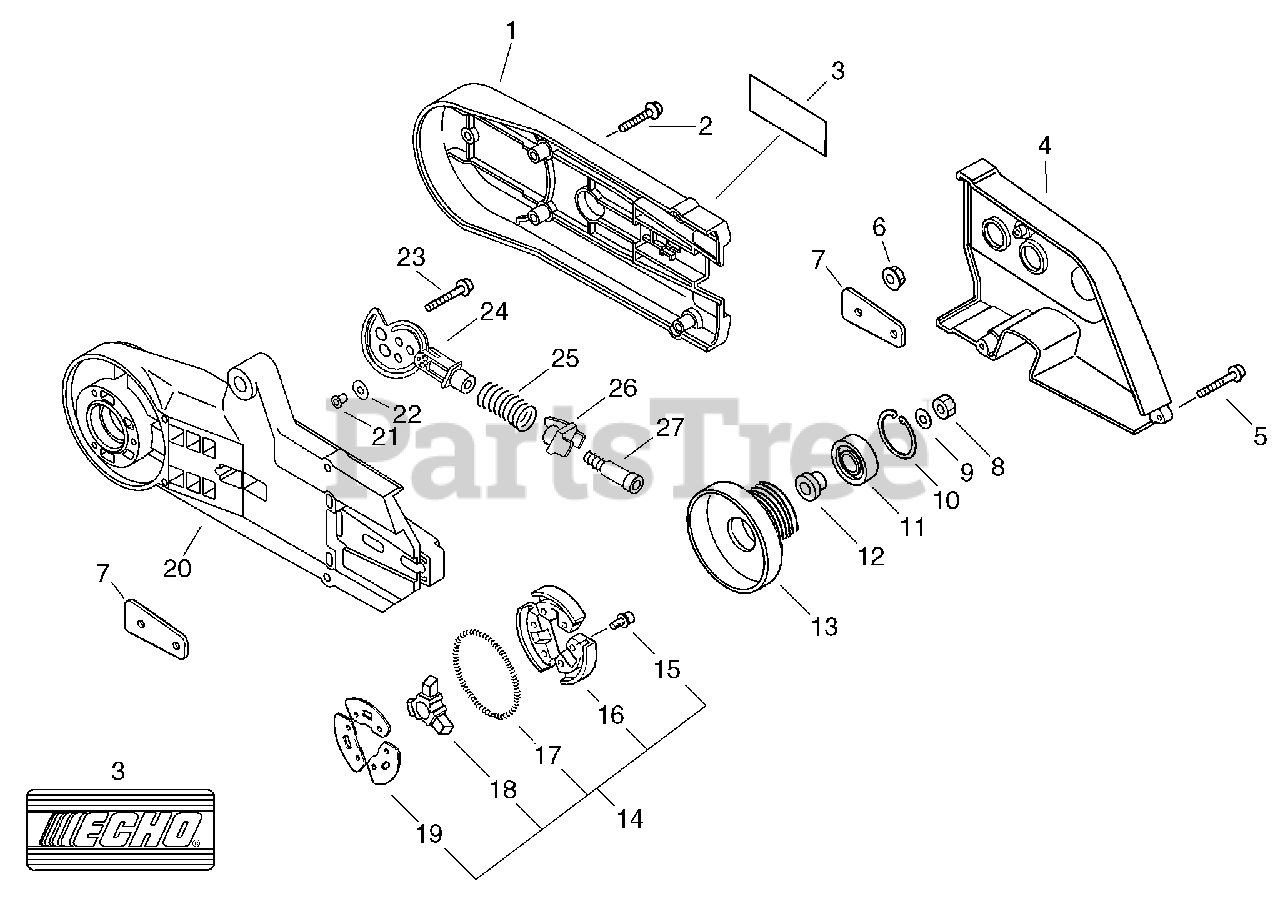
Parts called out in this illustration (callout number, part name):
1	COVER, GEAR
2	SCREW 5×25
3	LABEL - ECHO
4	COVER, V-BELT
5	SCREW 5×25
6	NUT, FLANGE M8×1.25
7	SPACER, ARM
8	NUT 8 LH
10	RING, SNAP 28
11	BEARING, BALL 6001 DDU
12	COLLAR - 10
13	DRUM, CLUTCH
14	CLUTCH ASSY
15	BOLT 4×6
16	SHOE SET, CLUTCH (3PCS)
17	SPRING, CLUTCH
18	BOSS, CLUTCH
19	PLATE, CLUTCH
20	ARM, CUTTER
22	WASHER, SPRING 8.5×16×0.5
23	BOLT 5×25
24	ADJUSTER, BLADE
25	SPRING, ADJUSTER
26	HOLDER, SPRING
